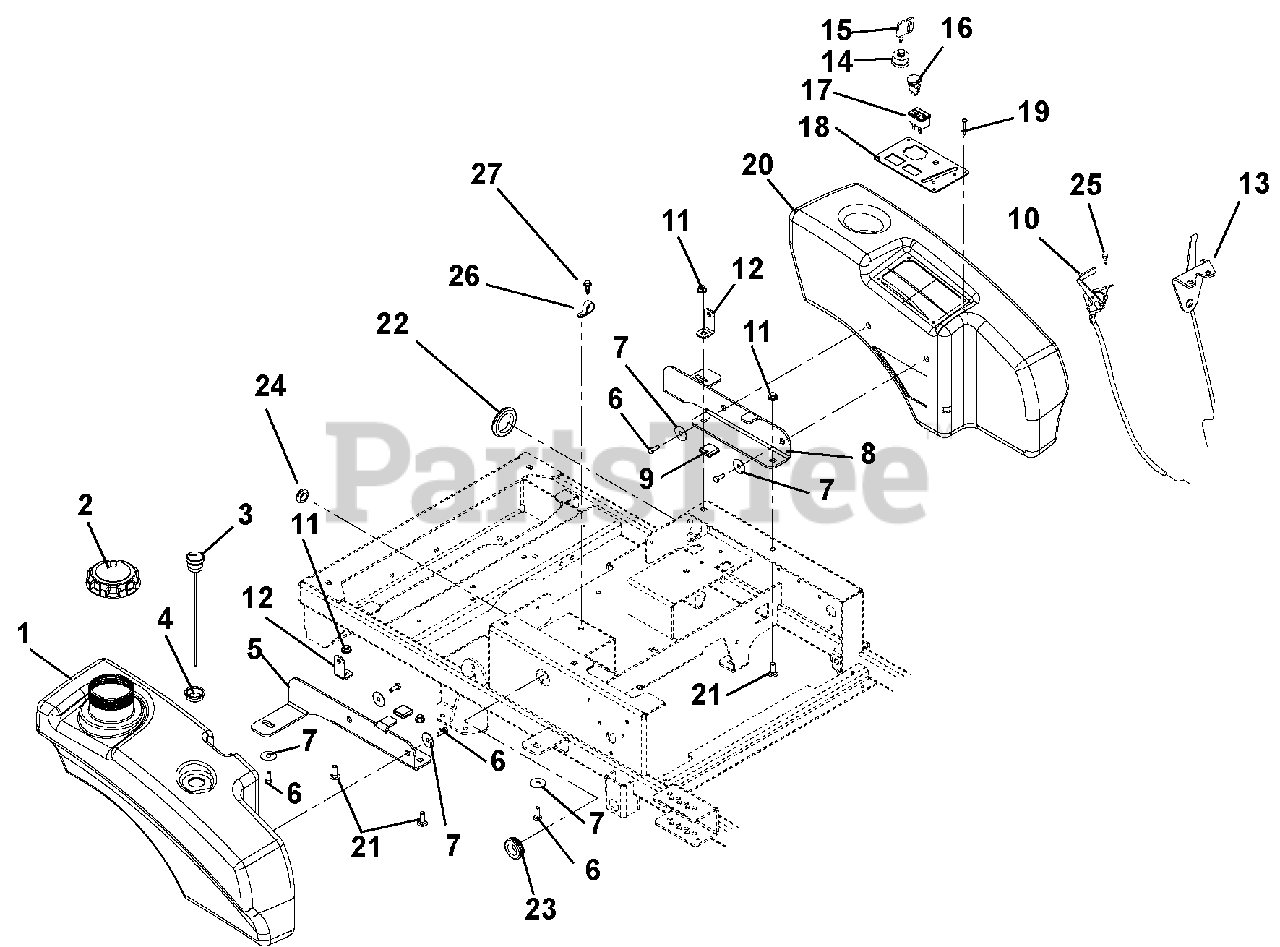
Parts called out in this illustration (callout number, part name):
1	Tank, XL
2	Fuel Cap
3	Gauge, Remote Fuel 10.0"
4	Grommet, Fuel Gage
5	Bracket, Right Hand Rear Tank Mount
6	Bolt, Serrated Hex Flange Washer Head .312-18 x .50
7	Washer, Flat Steel .347 x 1.254 x .048
8	Bracket, Left Hand Rear Tank Mount
9	Grip, Rubber
10	Cable, Throttle (915154 s/n 000426 and lower, 915156 s/n 000641 and lower, 915158 s/n 000368 and lower)
11	Nut, .38-16 Nyloc Flange
12	Bracket, Hood Pivot
13	Cable, Choke (915154 s/n 000426 and lower, 915156 s/n 000641 and lower, 915158 s/n 000368 and lower)
14	Key Switch
15	Key, w/cap
16	Switch, Clutch
17	Hour Meter, Digital
18	Control Panel
19	Rivet, Plastic .195 Diameter
20	Fender, XL
21	Bolt, Round Head Square Neck .38-16 x 1.00 Grade 5
22	Grommet, 2.00"
23	Grommet .125 x 1.000 ID
24	Grommet, Rubber 5/8 ID/1.13 OD
25	Screw, Tapping 10-24 x .50 Hex Washer Head Thread Rolling
26	Clamp, Cushioned Steel (915154 s/n 000427 and up, 915156 s/n 000642 and up, 915158 s/n 000369 and up)
27	Screw, Tap Hex Washer Head .38-16 x .5 (915154 s/n 000427 and up, 915156 s/n 000642 and up, 915158 s/n
